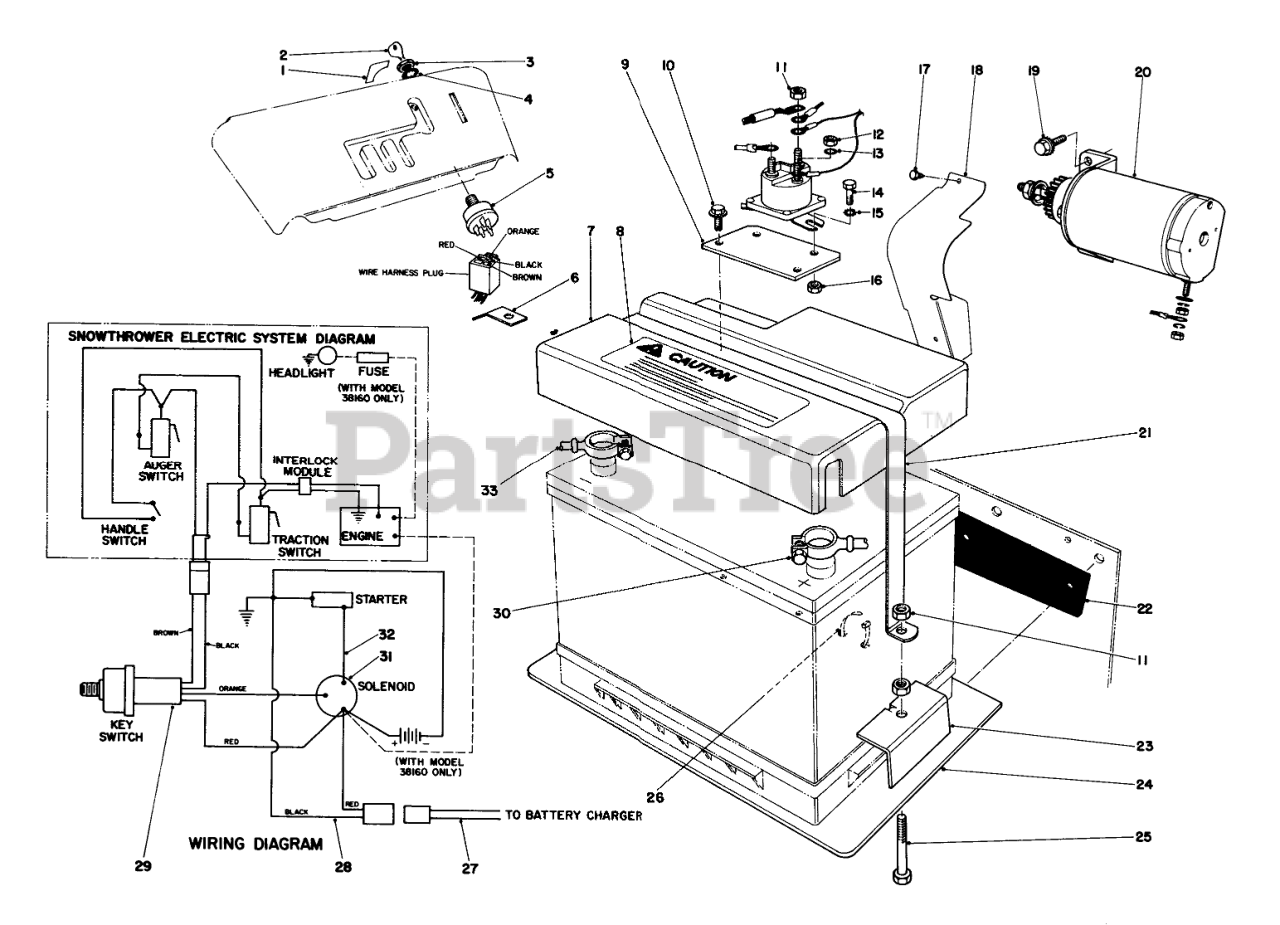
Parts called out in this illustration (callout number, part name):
1	Decal Switch
2	Key
3	NUT-HH
4	WASHER-TOOTH, INTERNAL
5	Starter Switch (Incl.Ref. #3 & 4)
6	Bracken Wire Clamp
7	Battery Cover (Incl. Ref. #8)
8	Decal-Caution
9	Bracket Solenoid
10	SCREW-HWH
11	NUT-HEX
12	NUT-HEX
13	WASHER-LOCK, INT
14	SCREW-HH
15	WASHER-LOCK/EXT
16	NUT-LOCK, NI
17	Hex Hd. Sems Screw
18	Pinion Shield
19	Screw-HH
20	Starter Motor & Pinion Assy.
21	Strap Battery
22	Batery Isolation Pad
23	BATTERY CLAMP
24	Battery Mounting Plate
25	SCREW-HH
26	TIE-CABLE
27	MALE WIRE ASM
28	FEMALE WIRE ASM
29	Wire Harness
30	BATT-SOLENOID CABLE
31	SOLENOID
32	STRT MTR-SOLNOID WIRE
33	BATT-GROUND CABLE
